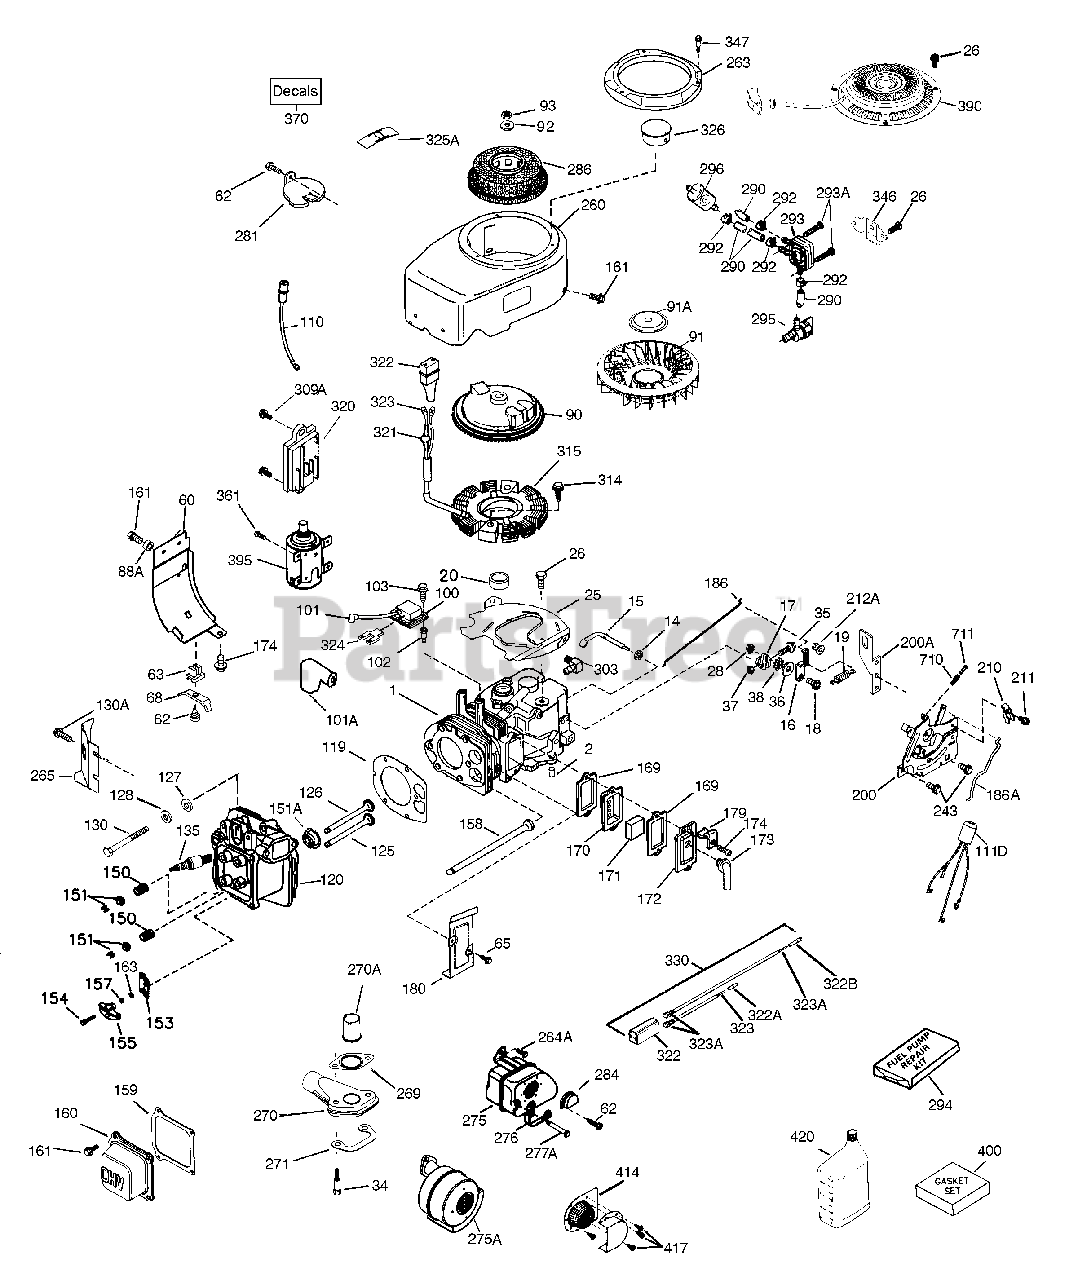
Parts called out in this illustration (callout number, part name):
1	"Cylinder (Incl. 2, 20 & 72A)
2	Dowel Pin
14	Flat Washer
15	Governor Rod
16	Governor Lever (Incl. 212A)
17	Governor Lever Clamp
18	Screw, T-15, 8-32 x 3/8"
19	Extension Spring
20	Oil Seal
25	Blower Housing Baffle
26	Screw, 1/4-20 x 19/32"
28	Lock Nut, 8-32
34	Screw, 5/16-18 x 1/2"
35	Screw, 10-32 x 3/4"
36	Lock Washer #8
37	Lock Nut, 10-32
38	Retaining Ring
41	Piston & Pin Assembly (Std) (Incl. 43 )
41	Piston & Pin Ass'y. (.010" OS) (Incl. 43)43)
41	Piston & Pin Ass'y. (.020" OS) (Incl. 43)43)
60	Blower Housing Extension
62	Screw, 8-32 x 3/8"
65	Screw, 10-24 x 9/16"
90	Flywheel (Incl. 91 & 91A)
91	Flywheel Fan
91A	Flywheel Retainer
92	Lock Washer
93	Flywheel Nut
100	Solid State Ignition (Incl. 101)
101	Spark Plug Cover
101A	Spark Plug Shield
102	Solid State Mounting Stud
103	Screw, T-15, 10-24 x 15/16"
110	Ground Wire
119	* Cylinder Head Gasket
120	Cylinder Head (Incl. 151A & 270A)
125	Exhaust Valve (Std.)
125	Exhaust Valve (1/32" OS)
126	Intake Valve (Std.)
128	Belleville Washer
130	Screw, 5/16-18 x 2-1/2"
130A	Screw, 5/16-18 x 17/32"
135	Resistor Spark Plug (RN4C) also avail able in Packaged Part #740069
150	Valve Spring
151	Valve Spring Keeper
151A	Intake Valve Seal
153	Push Rod Guide
154	Rocker Arm Stud (Order 730636A conver sion kit)
155	Rocker Arm
157	Lock Nut, 5/16-24
158	Push Rod
159	* Rocker Arm Cover Gasket
160	Rocker Arm Housing
161	Screw, T-30, 1/4-20 x 1/2"
163	Lock Washer
169	* Breather Gasket
170	Breather Body
171	Breather Element
172	Valve Cover
173	Breather Tube
174	Screw, 10-24 x 1/2"
180	Blower Housing Extension
186	Governor Link
186A	Choke Link
200	Control Bracket Incl. 203, 204 & 212A
210	Conduit Clip
211	Screw, 10-32 x 3/8"
243	Screw, 10-32 x 7/16"
260	Blower Housing
263	Trim Ring
264A	Muffler Brace Mounting Stud
265	Cylinder Head Cover
269	* Exhaust Manifold Gasket
270	Manifold (Opp Carb)
270A	Exhaust Port Liner
271	Locking Plate (Manifold)
275	Muffler
276	Locking Plate
277A	Screw, 5/16-18 x 4-1/2"
284	Exhaust Deflector
286	Cup & Screen
290	Fuel Line
292	Fuel Line Clamp
296	Fuel Filter (Incl. 292) also availabl e in Packaged Part #740093
314	Screw, 1/4-20 x 3/4"
315	Alternator Coil (3/5 Split) Incl. 321 - 323
322	Connector Body
323	Terminal
325A	Wire Clip
326	Screen Plug
330	Wire Harness
347	Screw, 10-32 x 9/16"
361	Screw, T-30, 5/16-18 x 1-21/32"
370	Decal - Air Screen Must Be Kept Clean
370	Decal - Important Lubrication - SAE 3
370R	Warning Decal (Bilingual)
395	Electric Starter Motor (12 Volt)
400	* Gasket Set Incl. items marked PK in n otes
420	SAE 30 4-Cycle Engine Oil (Quart)
710	Compression Spring
711	Screw, T-10, 6-32 x 41/64"
